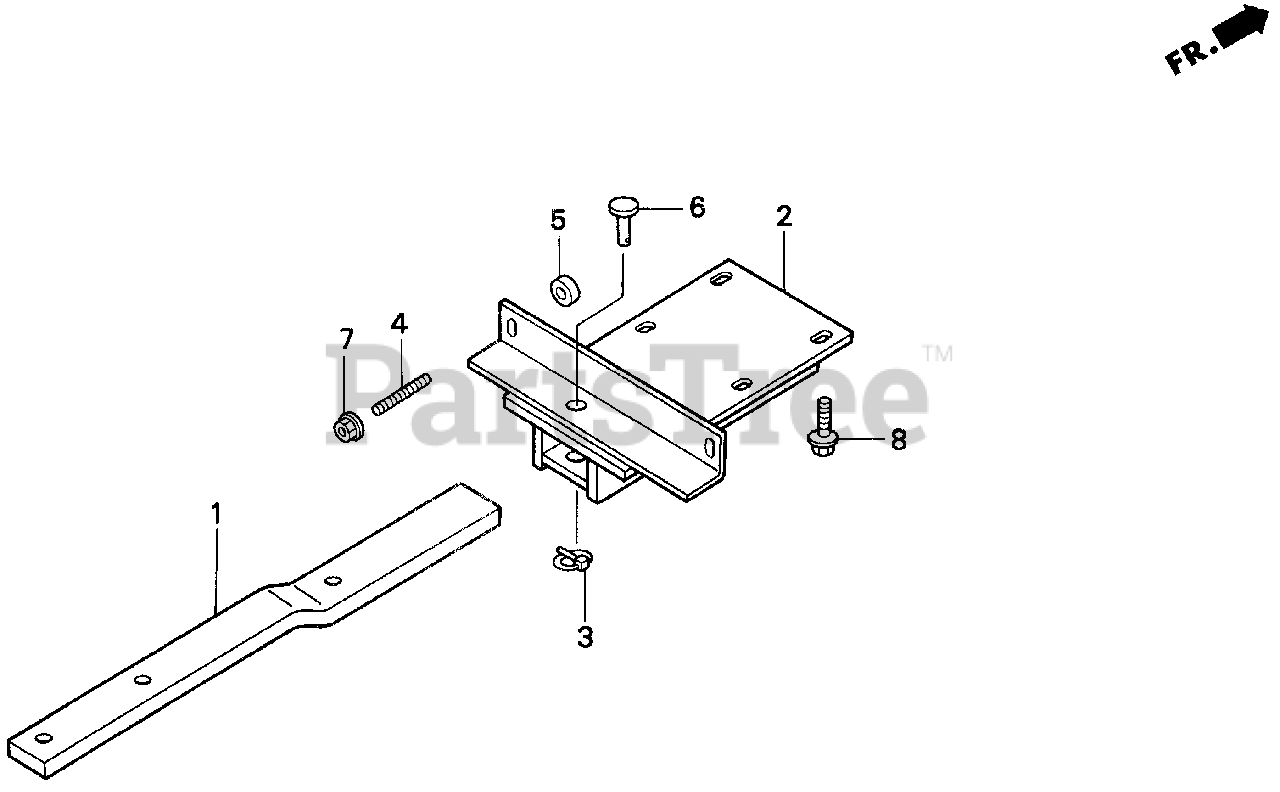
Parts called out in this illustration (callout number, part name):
1	BAR, DRAW
2	BRACKET, DRAW BAR
3	LINCHPIN ASSY.
4	BOLT, STUD (12X27) (NOT AVAILABLE)
5	WASHER, PLAIN (12MM)
6	PIN (19X83)
7	NUT, FLANGE (12MM)
8	BOLT, FLANGE (12X35)
